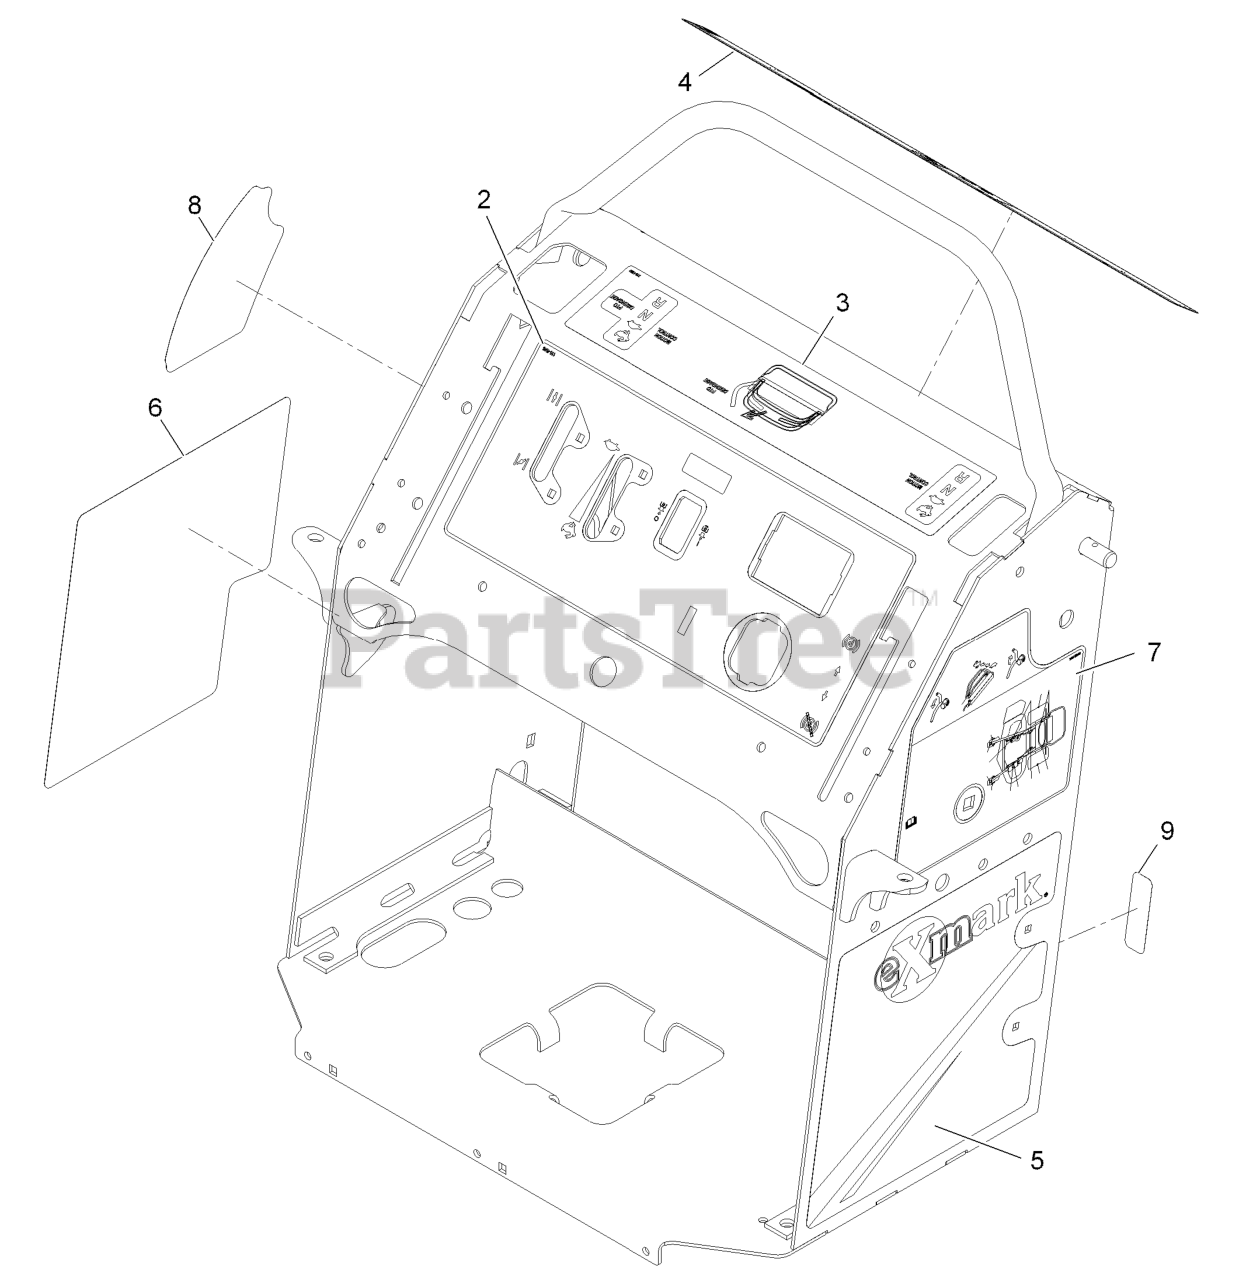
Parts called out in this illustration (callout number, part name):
2	DECAL-CONTROL PANEL
3	DECAL-MOTION CONTROL
4	DECAL-WARNING
5	DECAL-LH PANEL
6	DECAL-RH PANEL
7	DECAL-SERVICE AID
8	DECAL-HEIGHT OF CUT
9	DECAL-FUSE
